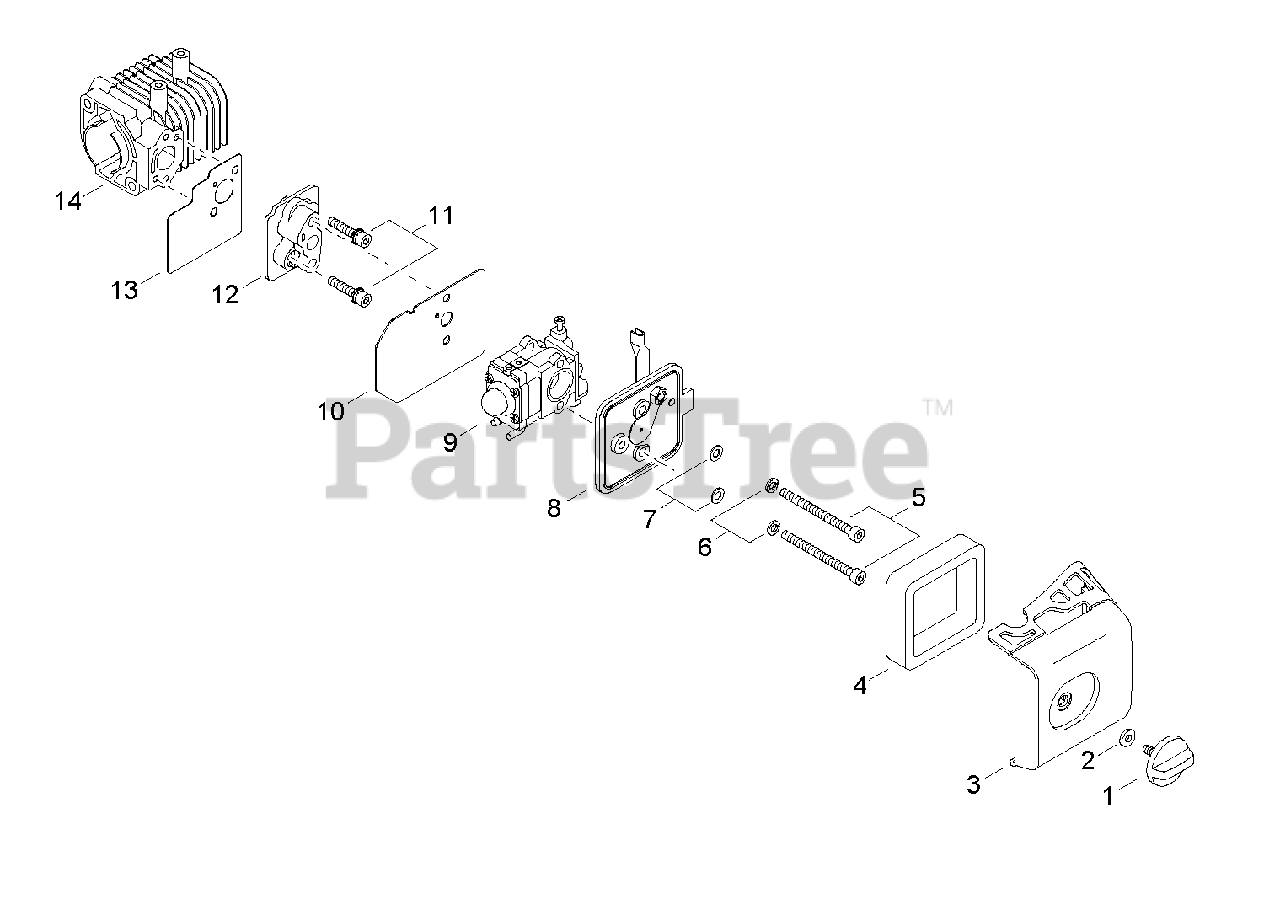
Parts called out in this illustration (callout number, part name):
1	THUMBSCREW
2	WASHER 5
3	COVER, AIR FILTER
4	FILTER, AIR
5	BOLT 5×55
6	WASHER, SPRING 5
7	WASHER, FLAT 5.5×10×0.8
8	CASE ASSY, AIR FILTER
9	CARBURETOR - WYJ-488
10	GASKET, CARBURETOR
11	BOLT M5×30
12	INSULATOR, INTAKE
13	GASKET, INTAKE
14	CYLINDER
